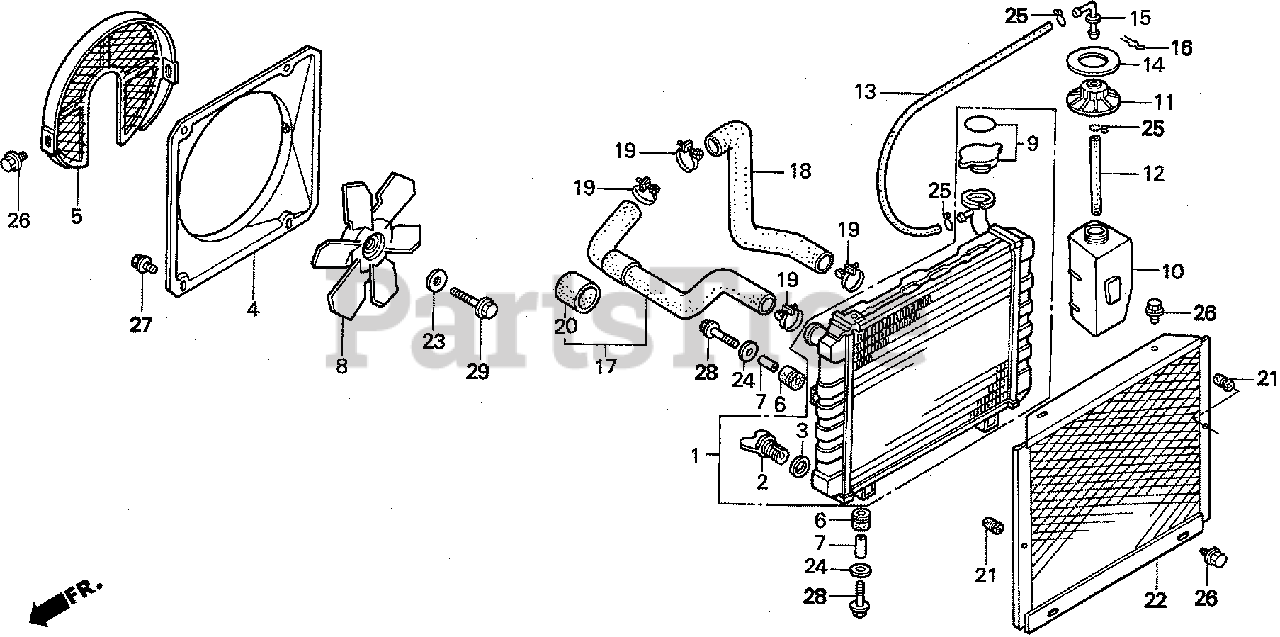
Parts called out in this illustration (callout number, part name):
1	RADIATOR
2	VALVE, DRAIN (TOYO)
3	GASKET, DRAIN (TOYO)
4	SHROUD
5	COVER, FAN
6	RUBBER, RADIATOR MOUNTING
7	COLLAR, DISTANCE
8	FAN, COOLING
9	CAP, RADIATOR (DENSO)
10	TANK ASSY., RESERVE
11	CAP, RESERVE TANK
12	HOSE, RESERVE TANK
13	TUBE, RESERVE TANK
14	MARK, RESERVE TANK
15	JOINT, RESERVE TANK
16	CLIP, RESERVE TANK JOINT
17	HOSE, WATER (UPPER)
18	HOSE, WATER (LOWER)
19	CLIP, WATER HOSE
20	PROTECTOR, HOSE
21	RUBBER B, BATTERY HOLDER
22	COVER, RADIATOR
23	WASHER, LOCK
24	WASHER, WHEEL (6MM)
25	CLIP, TUBE (C11)
26	BOLT, FLANGE (6X8)
27	BOLT, FLANGE (6X12)
28	BOLT, FLANGE (6X35)
29	BOLT, FLANGE (8X28)
